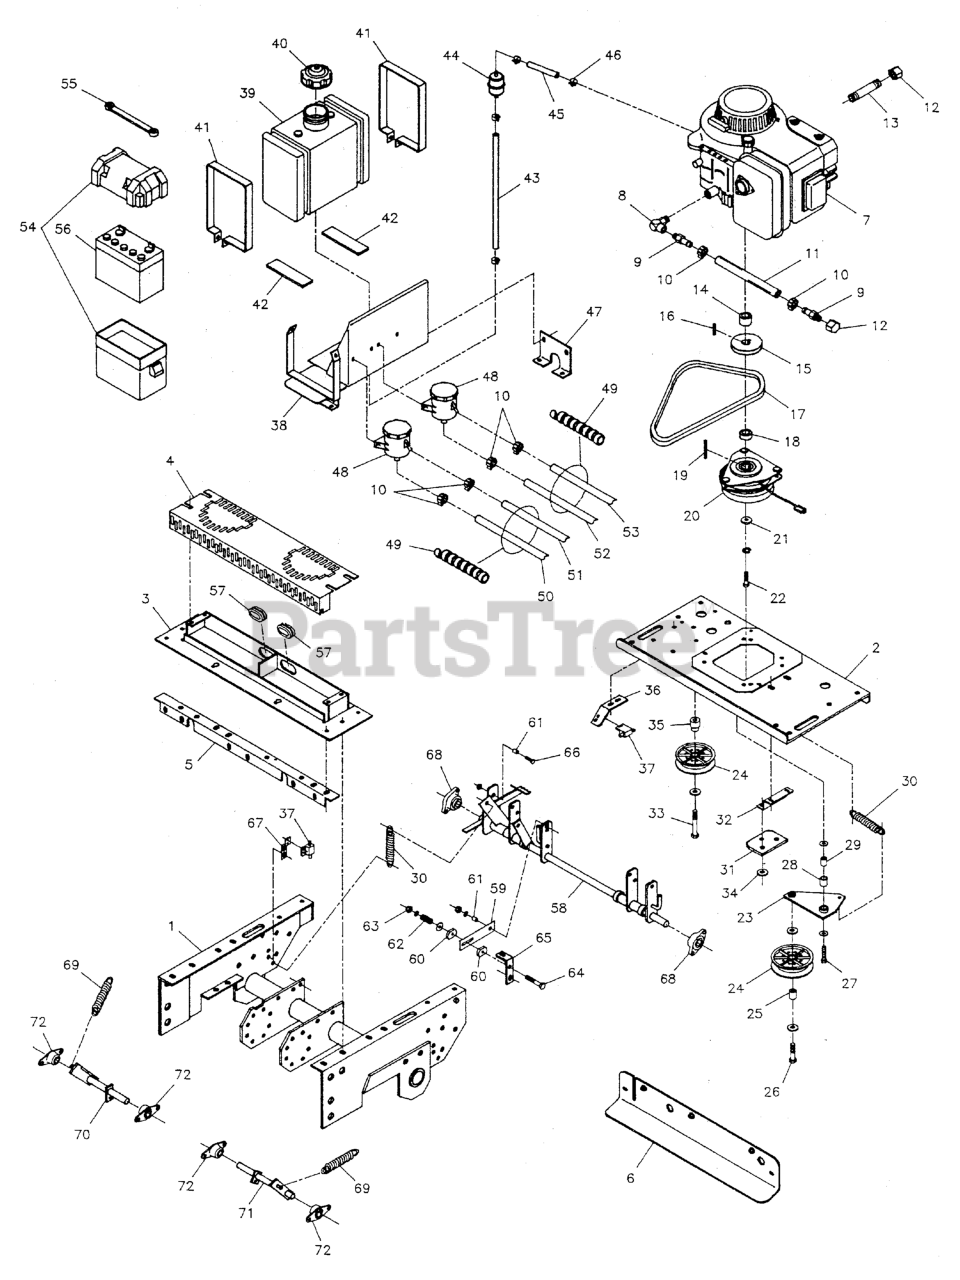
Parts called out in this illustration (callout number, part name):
1	ENGINE DECK
2	PLATE, Engine Deck
3	FAN SHROUD
4	FAN COVER
5	SUPPORT, Engine Deck
6	PLATE, Engine Deck Back
8	90 Degree Fitting
9	FITTING, 3/8NPT-1/2" Hose, Straight
10	CLAMP, #6 Hose
11	1/2" Hose, 18" Long
12	CAP, 3/8 NPT
13	Pipe Nipple
14	SPACER, 1.00 X 1.50 X 1.12
15	PULLEY, Crankshaft
16	KEY, 1/4" SQ. X 1-1/4
18	WASHER, 1" SAE
19	KEY, 1/4 SQ. X 1
20	CLUTCH, Electric, 1" Shaft
21	SPACER, .45 x 1.62 x .37
22	BOLT, M10 x 70MM
23	ASSM, MOUNT, GROUND DRIVE IDLER - RED
24	PULLEY, Backside Idler
25	INSERT, Bearing
26	BOLT, 1/2-20 X 1-1/2, GD5 CZ
27	BOLT, 5/16-18 x 1-3/4
28	BUSHING, Brass
29	SPACER, .32 x .75 x 1.06
30	SPRING, Extension
31	CLUTCH ANCHOR PAD
32	ANCHOR, Clutch
33	BOLT, 1/2-20 X 2-1/2" GD5 CZ
34	WASHER, Clutch Anchor
35	INSERT, Bearing Shoulder
36	MOUNT, Switch
37	SWITCH, PLUNGER, N.C.
38	MOUNT, Fuel Tank (Electric)
38	MOUNT, Fuel Tank (Manual)
39	TANK, FUEL, PLASTIC, 5 GALLON W/ FUEL LINE
40	Gas Cap
41	FUEL TANK STRAP
42	RUBBER PAD
43	1/4" Fuel Line, 18" Long
44	FUEL FILTER
45	1/4" Fuel Line, 4" Long
46	CLAMP, Hose
47	Gas Tank Mount Leg
48	RESERVOIR, Hydraulic
49	Protective Coil, 10" Long
50	HOSE, 3/8" PUSH-LOCK, 35.00"
51	HOSE, 3/8" PUSH-LOCK, 43.00"
52	HOSE, 3/8 PUSH-LOCK, 26.00
53	HOSE, 3/8" PUSH-LOCK, 37.00"
54	BATTERY BOX, W/ DRAIN HOLE
55	RUBBER STRAP
56	BATTERY, Lawn & Garden, 12V (BCIU1, 340 CCA)
57	GROMMET, 1-1/4"
58	Control Shaft
59	PLATE, Friction
60	PUCK, Brake
61	SLEEVE
62	SPRING, Compression
63	NUT, 5/16-18 Hex Nylon Lock
64	BOLT, 5/16-18 x 3
65	SUPPORT, Engine Deck
66	BOLT, 3/8-16 X 1" GD5 CZ
67	MOUNT, Switch
68	BEARING, Flange
69	SPRING, Extension
70	Brake Shaft Left
71	SHAFT, Brake, Left
72	BEARING, Flange
